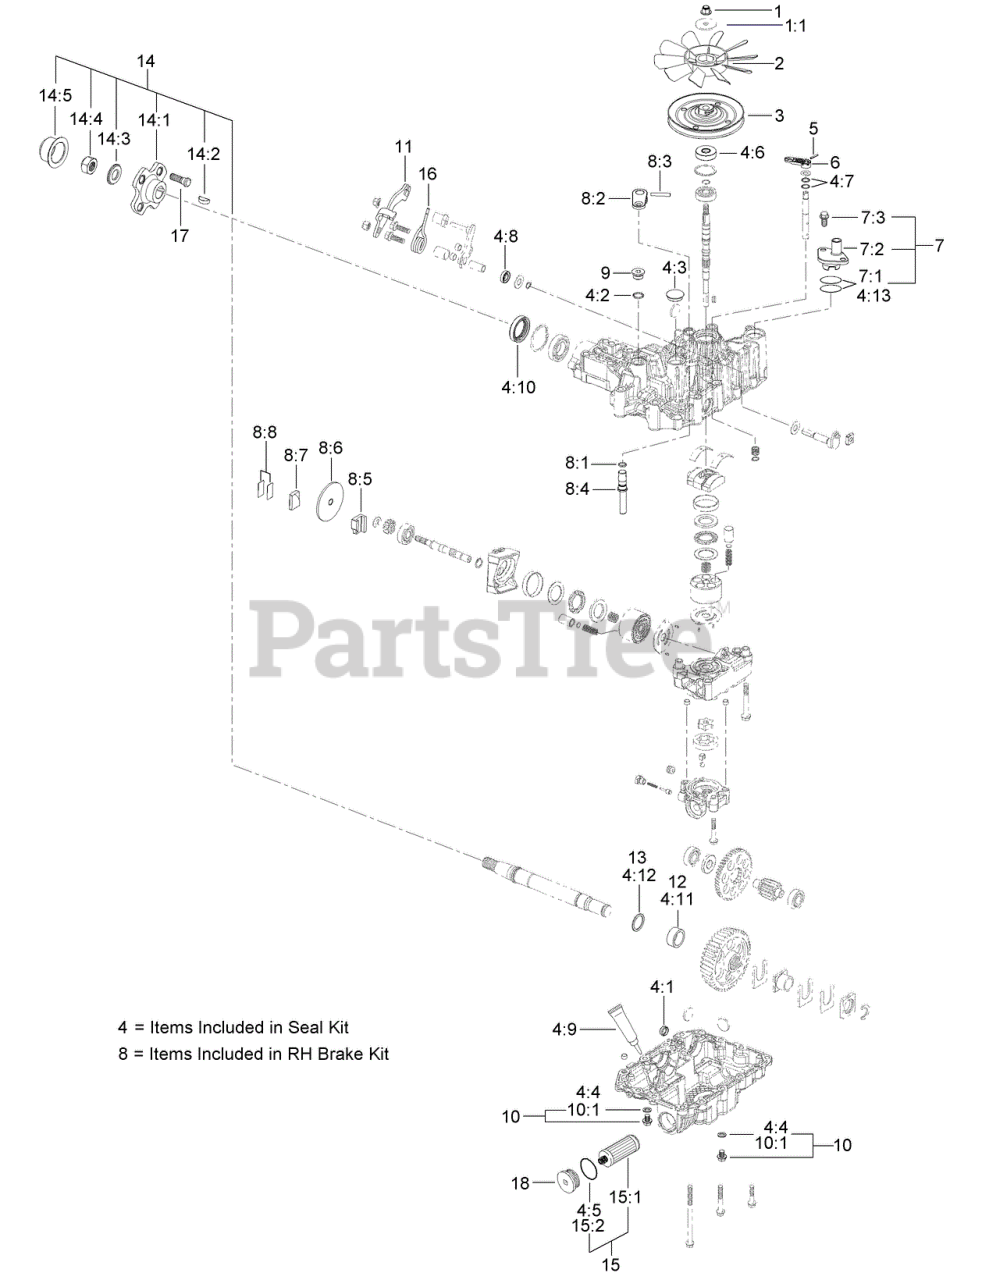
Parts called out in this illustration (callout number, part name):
1	NUT-LOCK
1:1	WASHER
2	FAN
3	PULLEY
4	SEAL KIT
4:1	CAP-SEALING
4:2	O-RING
4:3	CAP-SEAL
4:4	Seal-Washer
4:5	Packing
4:6	SEAL-SHAFT
4:7	Deck ASM
4:8	Deck ASM
4:9	SEALANT
4:10	SEAL-AXLE
4:11	SLEEVE
4:12	WASHER
4:13	Packing
5	PIN
6	LEVER-BYPASS
7	EXPANSION FITTING KIT
7:1	SEAL-FITTING, EXPANSION
7:2	Fitting
7:3	BOLT-FLANGE
8	RH BRAKE KIT
8:1	Deck ASM
8:2	ARM-BRAKE
8:3	Deck ASM
8:4	SHAFT-BRAKE
8:5	ACTUATOR-BRAKE
8:6	DISC-BRAKE
8:7	SHOE-BRAKE
8:8	SHIM KIT
9	CAP-OIL
10	DRAIN BOLT KIT
10:1	Seal-Washer
11	LEVER-CONTROL, RH
12	SLEEVE
13	WASHER
14	AXLE FLANGE KIT
14:1	Deck ASM
14:2	Key-Woodruff
14:3	Deck ASM
14:4	NUT-LOCK
14:5	NUT-CAP
15	HYDRO FILTER KIT
15:1	FILTER
15:2	O-RING
16	SPRING-TORSION
17	STUD-WHEEL
18	CAP-OIL FILTER
